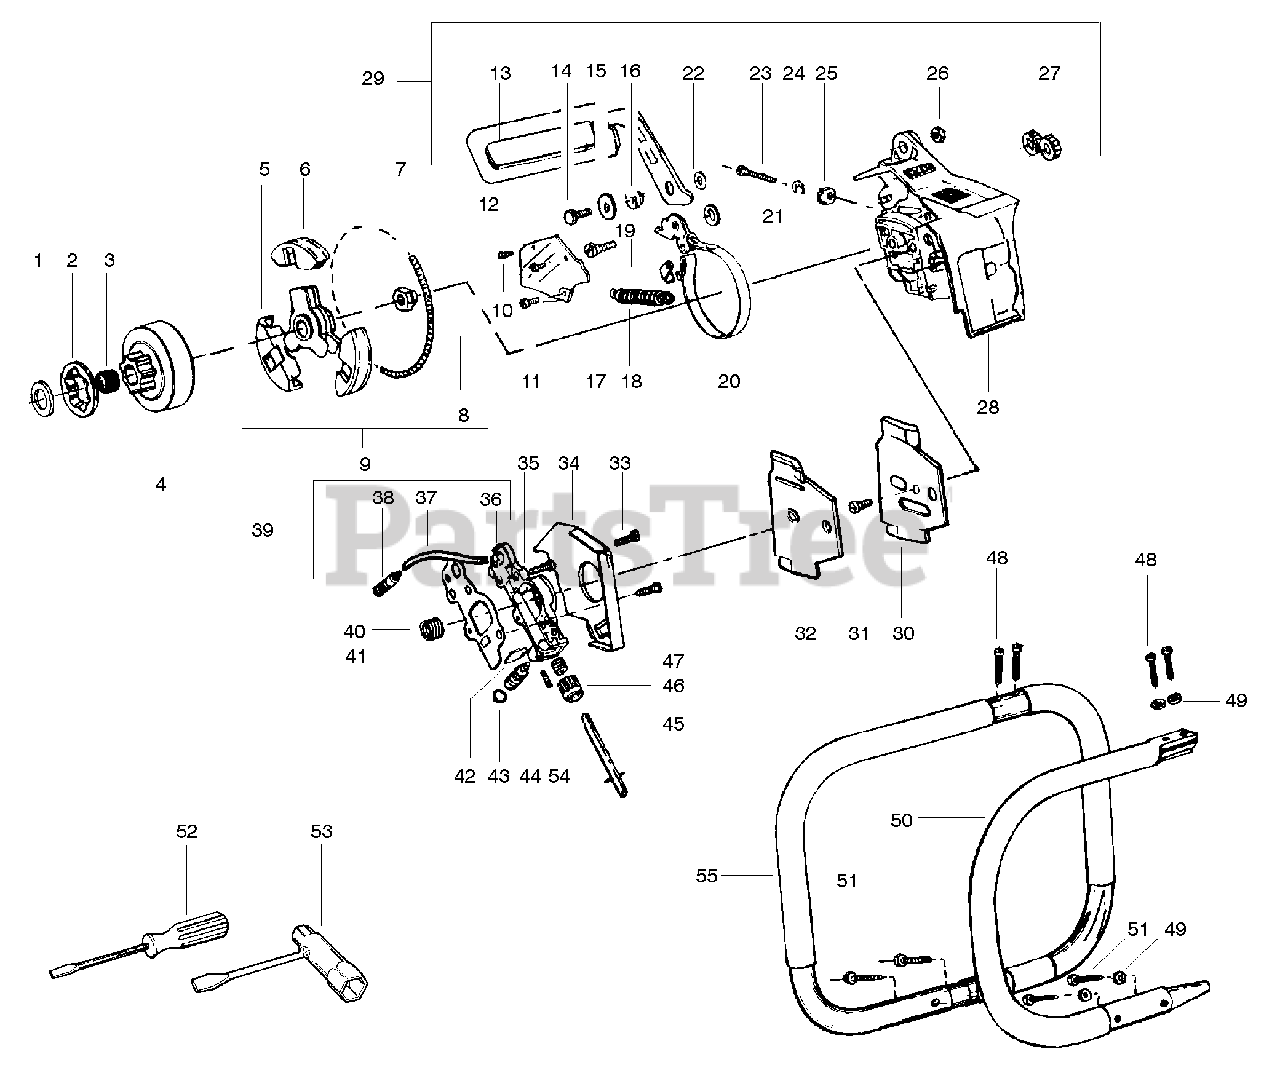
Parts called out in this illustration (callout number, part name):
1	Thrust Washer
2	Rim Sprocket (3/8 7 tooth)
4	Clutch Drum
5	Clutch Shoe
6	Clutch Driver
8	Clutch Spring
9	Clutch Ass'y.
13	Kickback Guard Assy.
17	Shoulder Bolt
19	Locking Plate
20	Band Ass'y.
24	Retaining Ring
27	Strut Nut
28	Clutch Cover & Tension
29	Chain Brake Ass'y.
30	Guide Plate-Outer
31	Terminal Screw
32	Guide Plate-Inner
34	Dirt Shield
36	Oil Pump Ass'y.
38	Oil Pickup Ass'y.
39	Oil Pump Ass'y.
40	Wire Worm
44	Adjusting Screw
45	Plunger Ass'y.
47	Plunger Spring
50	Front Handle Kit
52	Screwdriver
53	Combination T Wrench
54	Roll Pin
55	Front Handle Full Wrap
